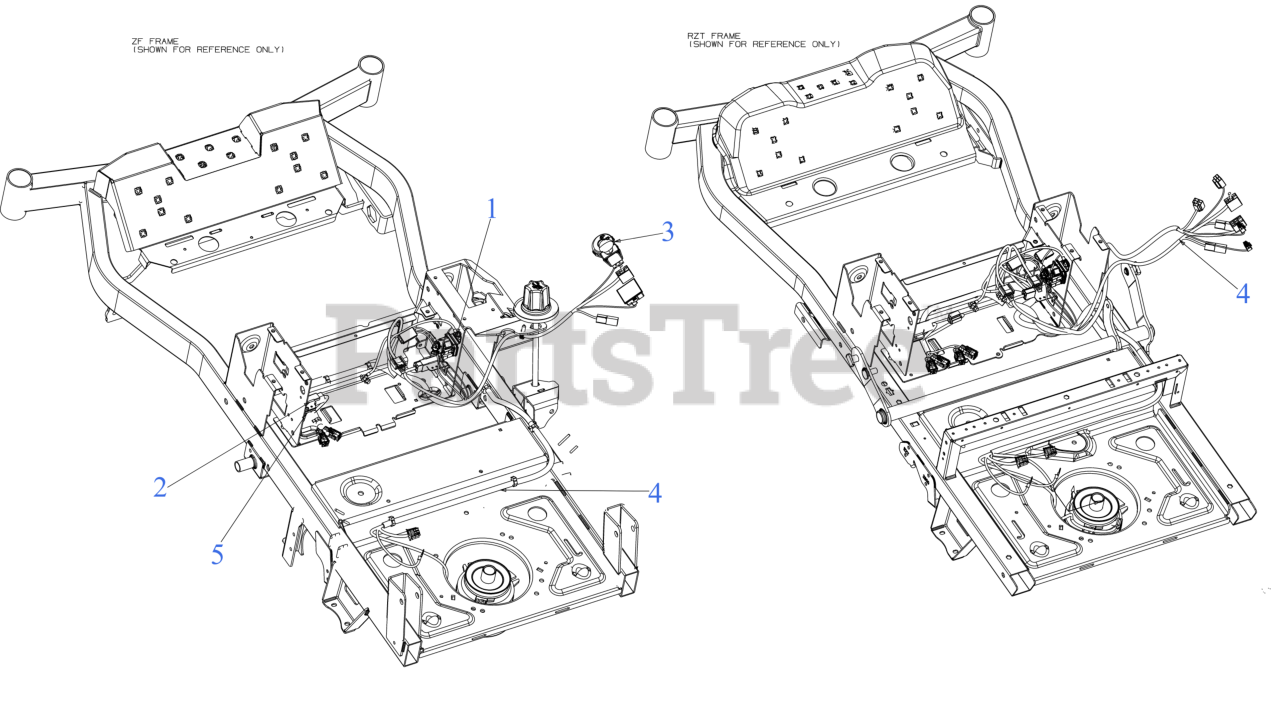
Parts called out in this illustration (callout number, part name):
1	SCREW 1/4-20X.625
2	INTERLOCK SWITCH (NO/NC)
3	KEY SWITCH (3 POS 6 PIN)
4	HARNESS (EPTO/HM/SOL/AGM)
5	SHOULDER SCREW
